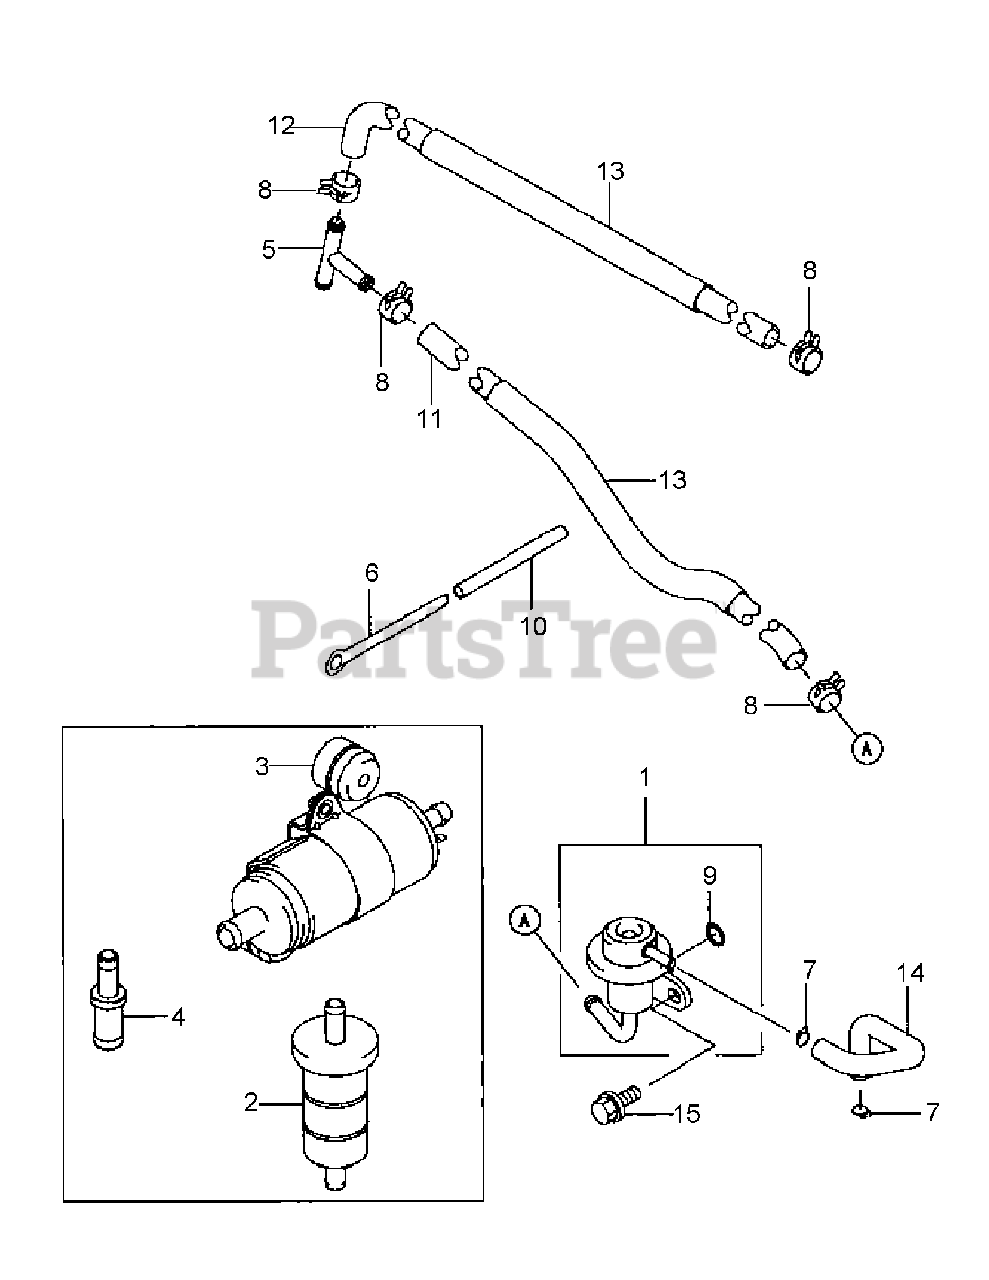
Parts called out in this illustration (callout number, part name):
1	FUEL REGULATOR
2	FUEL FILTER
8	CLAMP
9	O-RING FUEL REGULATOR
15	FLANGED BOLT
